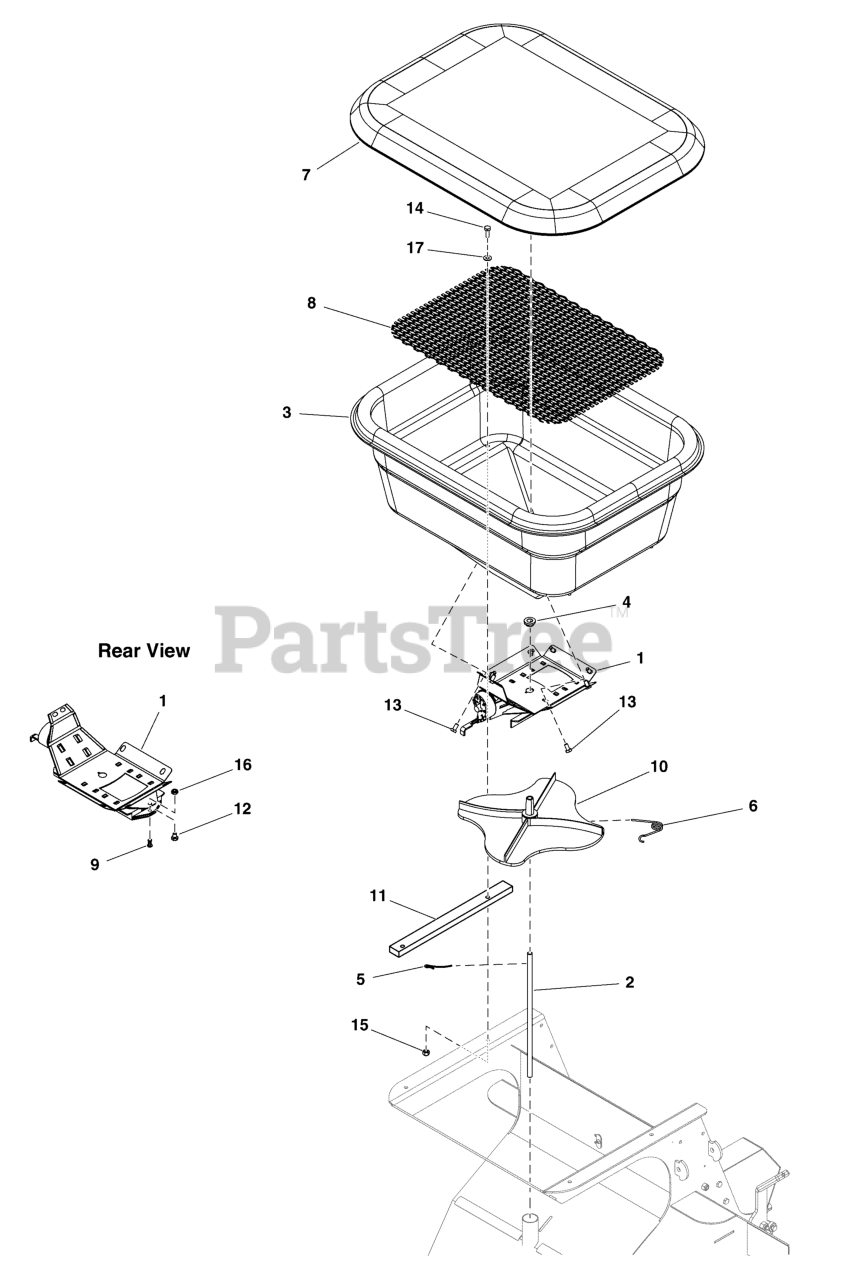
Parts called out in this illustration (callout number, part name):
1	ASSEMBLY,GATE,COMPLET
2	KIT, PLATTER SHAFT COUPLING
2	SHAFT, Platter
3	HOPPER, 220 LBS
4	BUSHING, HOPPER SPREADER
5	CLIP, SPINNER AGITATOR
6	CLIP, SPREADER SPINNER
7	COVER, HOPPER, MODEL 220
8	HOPPER, SCREEN, MODEL 220 LBS
9	FITTING, SWIVEL ACCUWAY
10	PLATTER, SPINNER, REDUCED CLEARANCE
11	SPACER, ROVER XC HOPPER
12	SCR-CAP, HEX .250"-20 X .375" SS188 SPC
13	SCR-CAP, HEX .250"-20 X .500" SS188
14	SCR-CAP, HEX .250"-20 X 1.500" SSF593C
15	NUT-HEX-NYLK, .250"-20 SS188
16	NUT-HEX-NYLK, .250"-20 TH SS188
17	WSHR-STL, FLT .281" X .625" X .050" IS SS188
